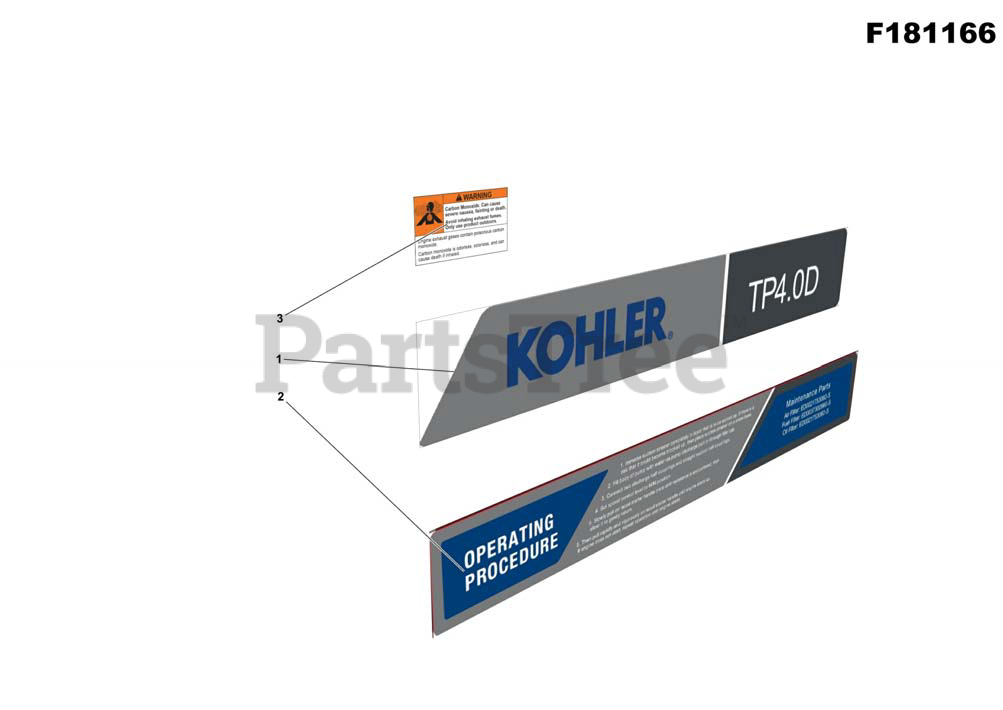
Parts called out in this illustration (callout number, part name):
1	Sticker (Kohler-TP4.0D-Left)
2	Sticker (Kohler-TP4.0D)
3	Sticker (Kohler-Warning)
